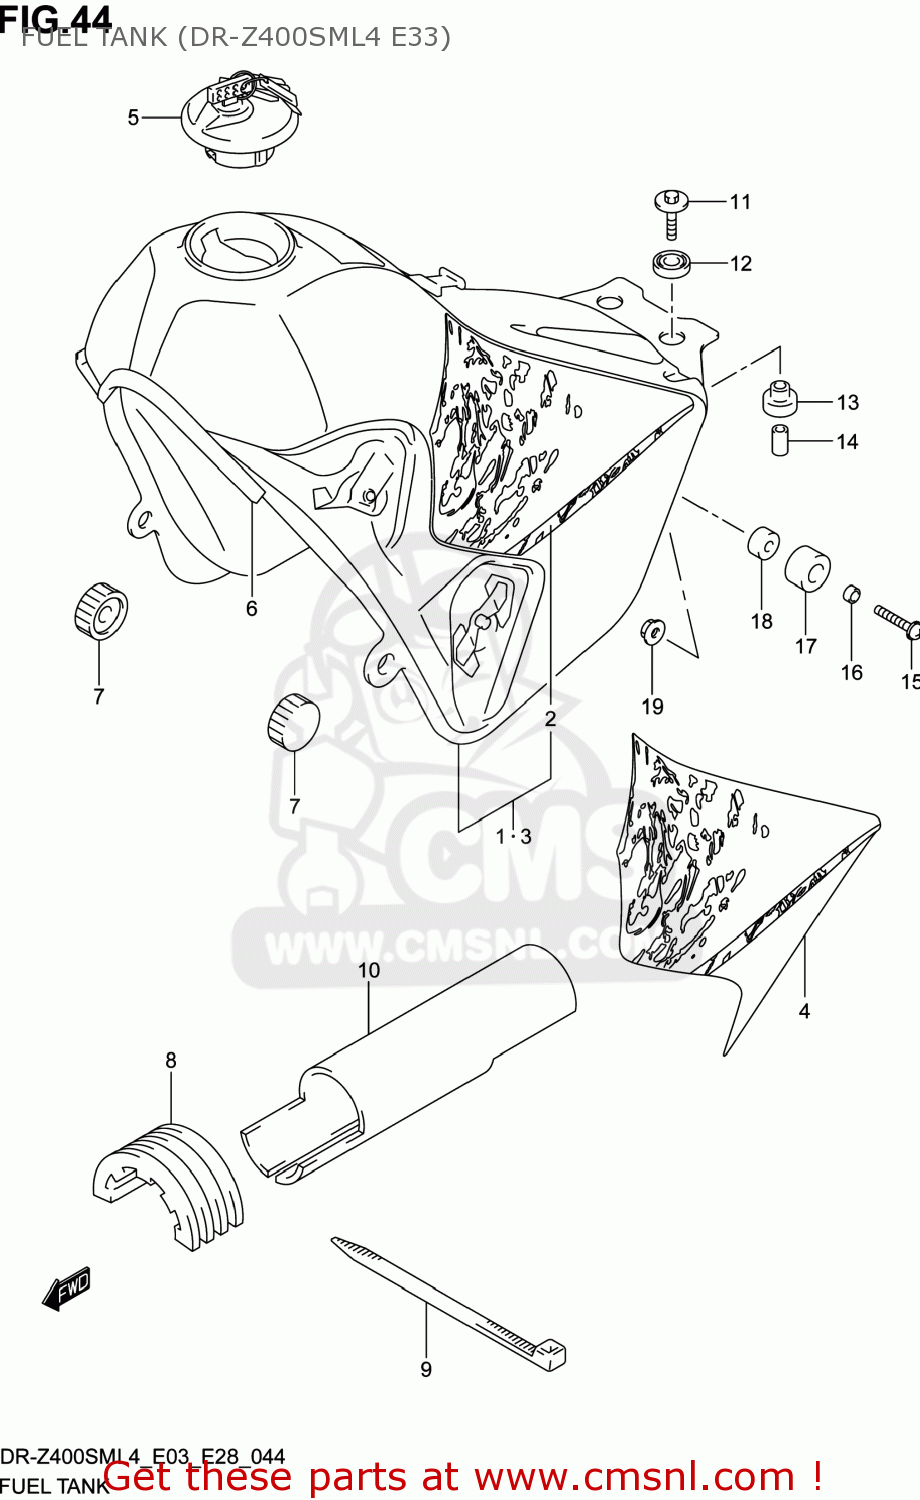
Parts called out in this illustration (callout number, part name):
1	TANK ASSY,FUEL
2	TAPE SET,FUEL TANK
3	TANK ASSY,FUEL
4	TAPE SET,FUEL TANK
5	CAP SET,FUEL TANK
6	MOLDING
7	CUSHION
8	CUSHION,FUEL TANK
9	CLAMP(L:300)
10	SHIELD,FUEL TANK
11	BOLT(6X30)
12	CUSHION
13	CUSHION
14	SPACER(6.5X9X18)
15	SCREW
16	SPACER(6.5X20X9)
17	CUSHION
18	SPACER(6.5X9X5)
19	NUT
